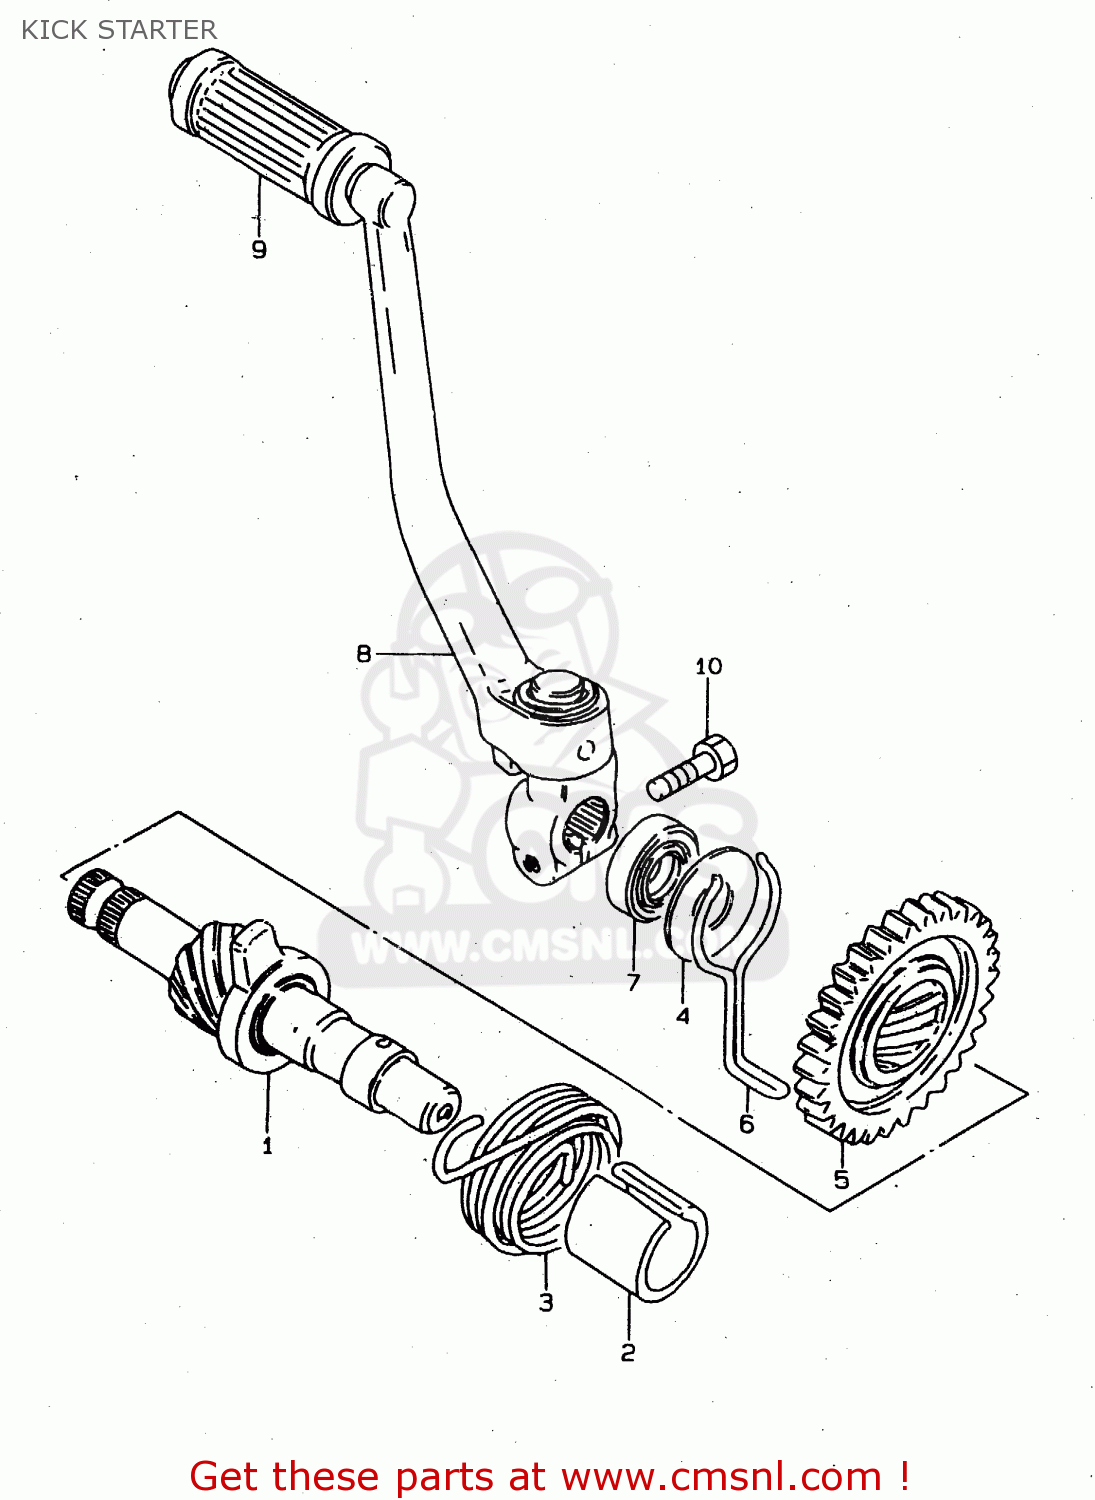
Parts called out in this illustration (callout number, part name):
1	SHAFT,KICK STARTER
2	GUIDE,KICK STARTER SFT SPRING
3	SPRING
4	WASHER
5	GEAR,KICK STARTER DRIVE(NT:30)
6	RETAINER,SNAP
7	SEAL,OIL(14X24X6)
8	LEVER ASSY,KICK STARTER
9	RUBBER,KICK STARTER PEDAL
10	BOLT
